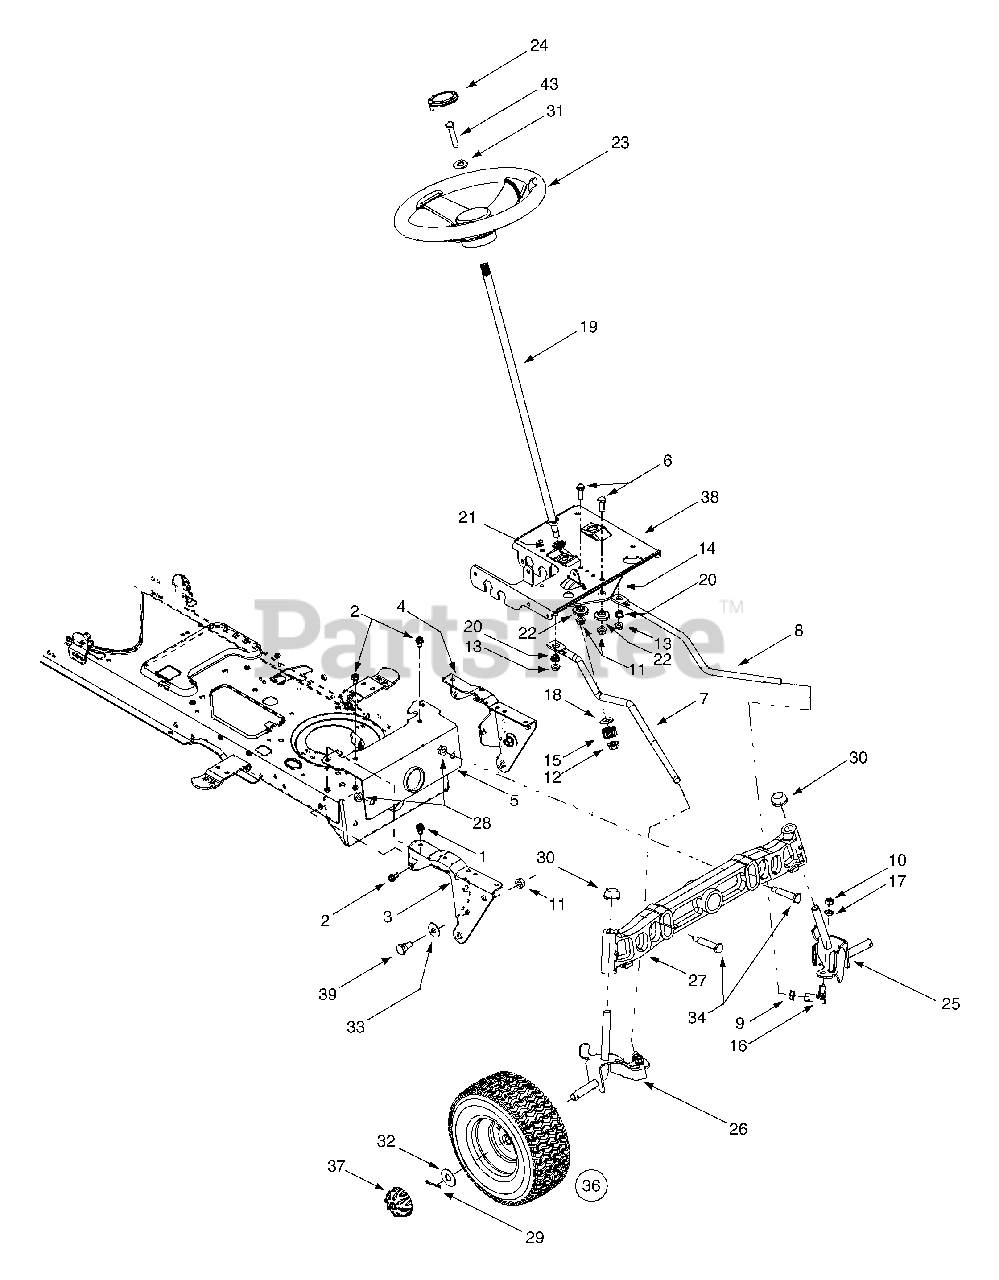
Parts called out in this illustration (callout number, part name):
1	Self-tapping Screw, 5/16-18 x .75
2	Self-tapping Screw, 16-18 x .625
6	Hex Cap Screw, 3/8-16 x 1 (Grade 5)
7	RH Drag Link
9	Jam Nut, 7/16-20 (Grade 2)
10	Hex Nut, 3/8-24 (Grade 2)
11	Flange Lock Nut, 3/8-16
12	Flange Lock Nut, 7/16-20
13	Flange Lock Nut, 5/16-18
14	Steering Gear, 11/90 Ratio
15	Steering Pinion Gear
16	Ball Joint, 7/16-20
17	Lock Washer, 3/8
18	Flat Washer, .51 x 1.12 x .06
19	Steering Shaft, .625 OD x 24.4
20	Plastic Bushing, .38 ID
21	Hex Flange Bearing, 5/8
22	Shoulder Spacer, .38 ID
23	Steering Wheel, Soft Grip, Three Spoke
24	Steering Wheel Cap, Round
25	LH Axle Assembly, .625 Dia. (Model LT-1650)
25	LH Axle Assembly, .750 Dia. Model LT-1850)
26	RH Axle Assembly, .625 Dia. (Model LT-1650)
26	RH Axle Assembly, .750 Dia. Model LT-1850)
27	Cast Iron Pivot Bar w/ Fittings, .625 (Model LT-1650)
27	Cast Iron Pivot Bar w/ Fittings, .750 (Model LT-1850)
28	Flange Lock Nut, 3/8-16
30	Push Cap, .750
31	Bell Washer, .34 x .872
32	Flat Washer, .635 x 1.589 x .06
33	Bell Washer, .39 x 1.13 x .062
34	Shoulder Screw, .5 x 2.2, 3/8-16
35	Hex Bolt, 5/16-18 X 1
37	Hub Cap
39	Shoulder Screw, 3/8-16
43	Hex Bolt 5/16-18 x 1" Lg.
